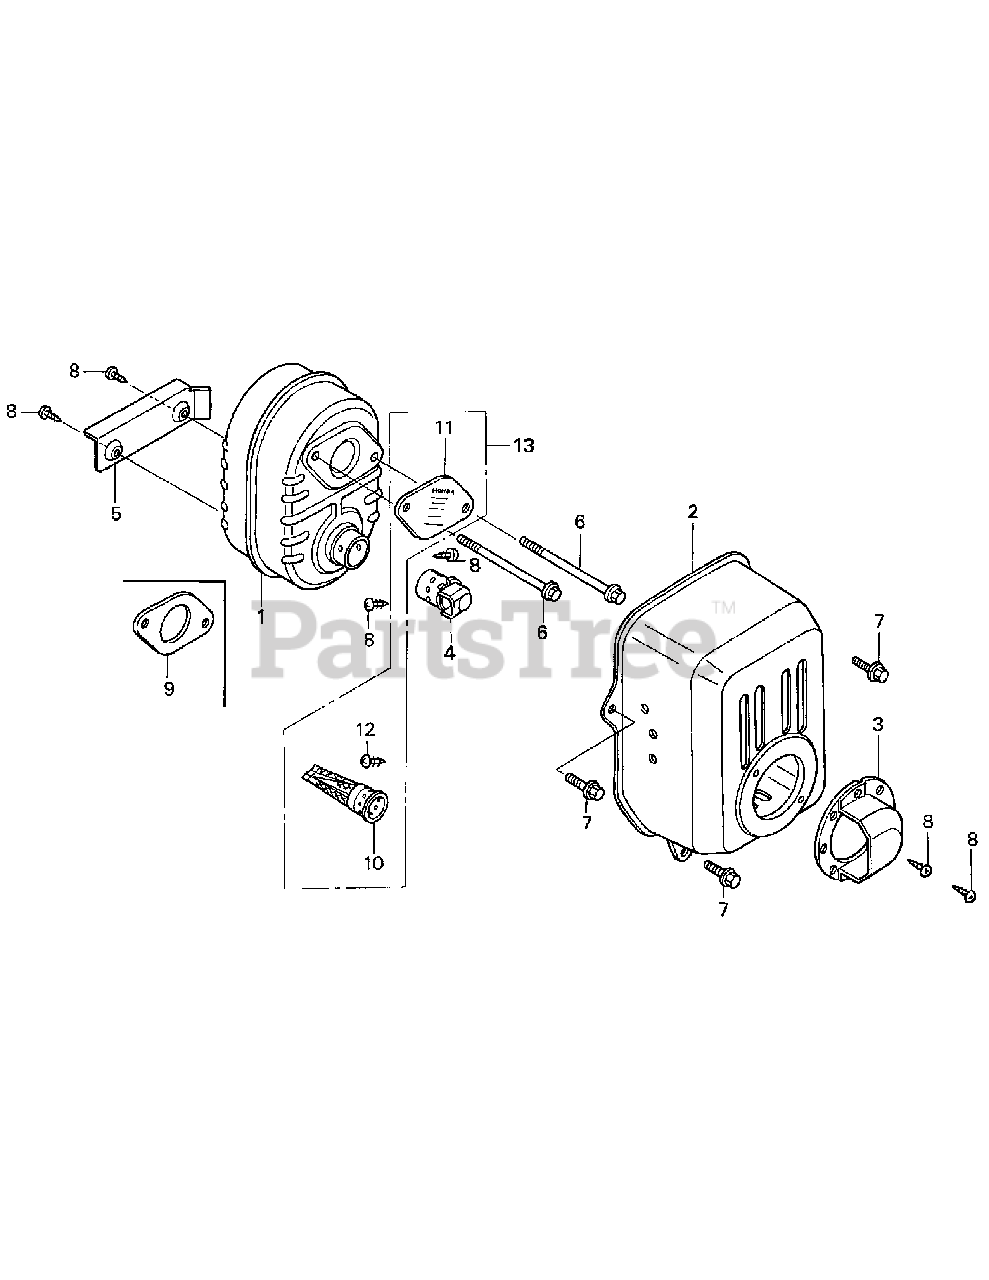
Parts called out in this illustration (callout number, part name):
2	PROTECTOR, MUFFLER
5	SHROUD, MUFFLER
6	BOLT, FLANGE (6X79) (CT200)
7	BOLT, FLANGE (6X12) (CT200)
8	SCREW, TAPPING (4X6)
9	GASKET, MUFFLER
10	ARRESTER, SPARK
11	PLATE, ARRESTER NUMBER
12	SCREW, TAPPING (4X6)
13	ARRESTER KIT, SPARK
